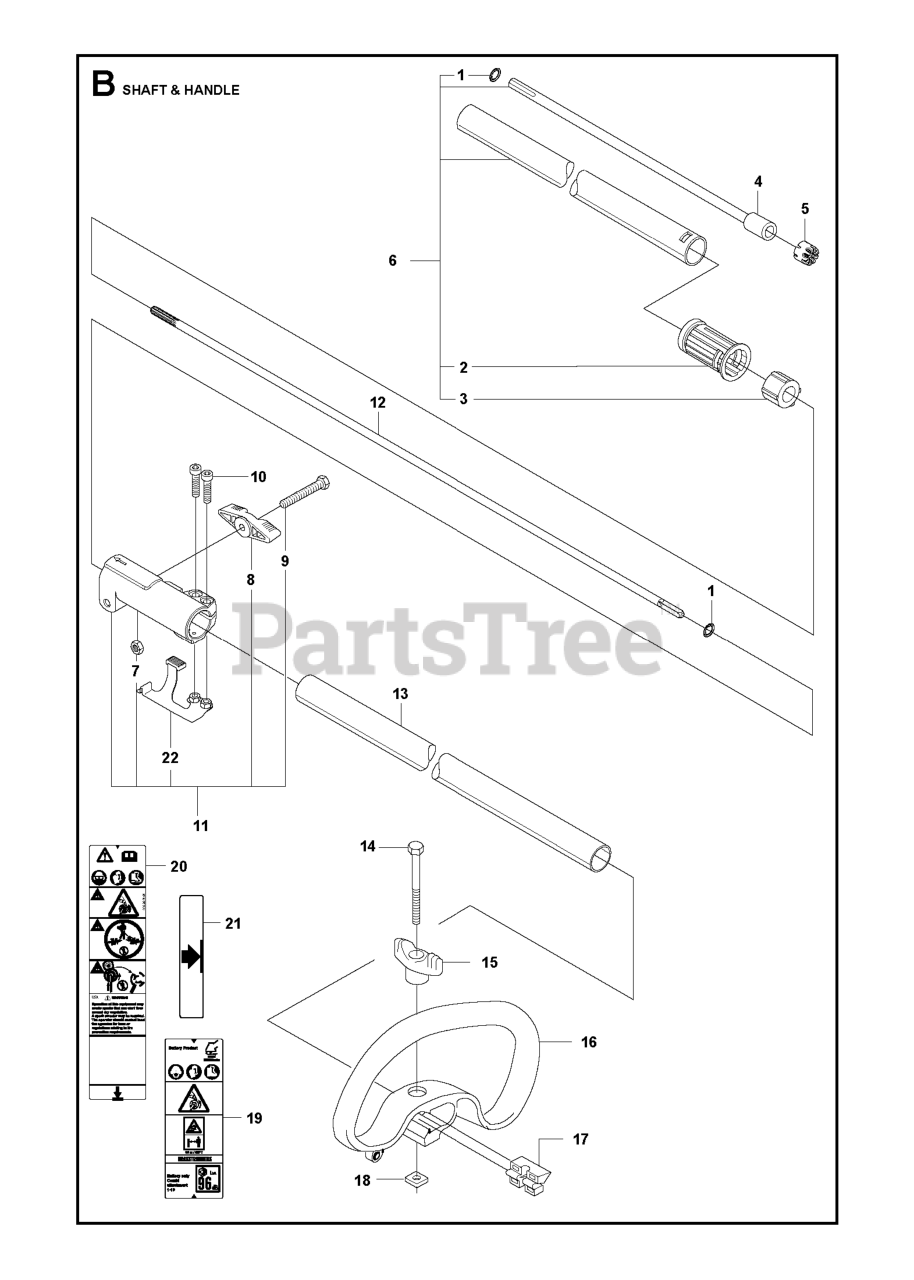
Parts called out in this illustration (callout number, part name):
6	TUBE
8	KNOB CLAMPING SLEEVE
9	BOLT FLANGE
11	CLAMPING SLEEVE ASSY
12	Drive Shafts
14	SCREW M6X50
17	SPACER PLASTIC
20	LABEL WARNING TRIMMERS AND BRU
21	DECAL ARROW
22	LOCKING PLATE ASSY CLAMPING SL
